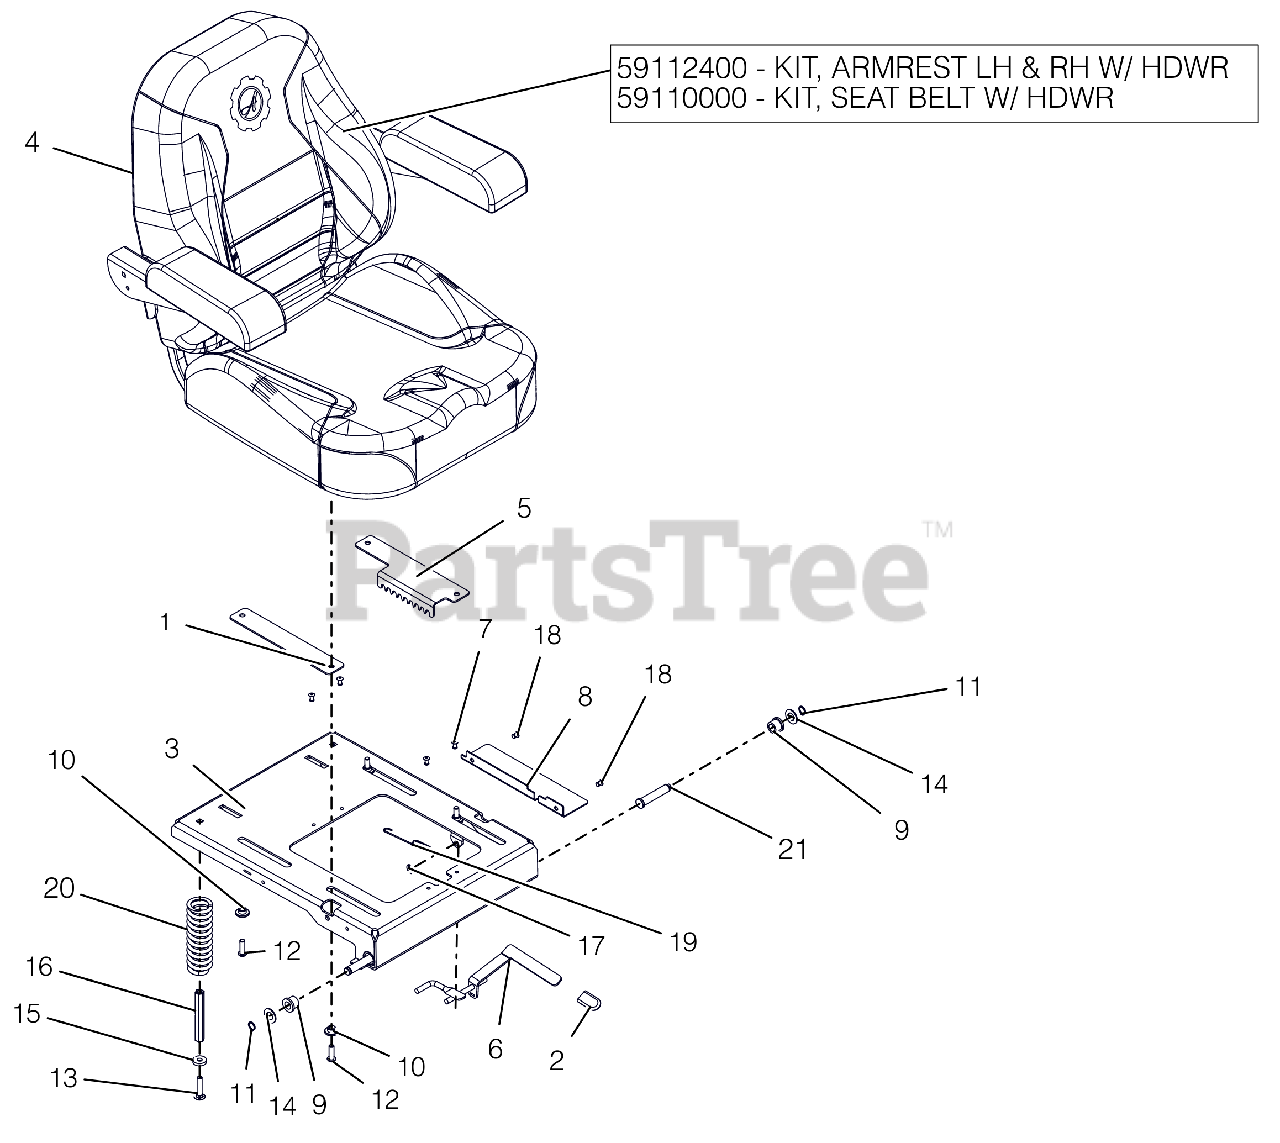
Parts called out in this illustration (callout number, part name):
1	PLATE, ADJUSTABLE SEAT SLIDE
2	GRIP, SEAT LEVER, GREY
3	WLDMT, SEAT PLATE HD
4	SEAT, APEX
4	KIT-LH & RH ARM REST-05124700
4	KIT-SEAT BELT REPLACE-05007300
5	PLATE, HD SEAT ADJUSTMENT
6	WLDMT, SEAT SLIDE LEVER
7	RIVET, #66 STEEL POP PD BLACK
8	GUARD, SEAT PLATE
9	BSHG, FLG .516X.750X.625X.937
10	BSHG-FLG .32X.500X.344X.880
11	RG-RTNG-EXT .500X.050 (SNAP)
12	SCR-SKH .31-18X1.0 BTNHD YWZC
13	@BLT-RDHDSQNK .31-18X1.50 G5YZ
14	WSHR-FL-STL.531X1.00X.063 YWZC
15	WSHR-FL-STL .328X.87X.179 YWZC
16	NUT, COUPLING 5/16X18 X 3.75
17	NUT-PUSH .312
18	RIVET, .1875 AL/AL .126-.250
19	SG-TENS .06X.482X5.35
20	SPRING, COMPRESSION SEAT 224LB
21	PIN, SEAT PIVOT -.500X2.31
